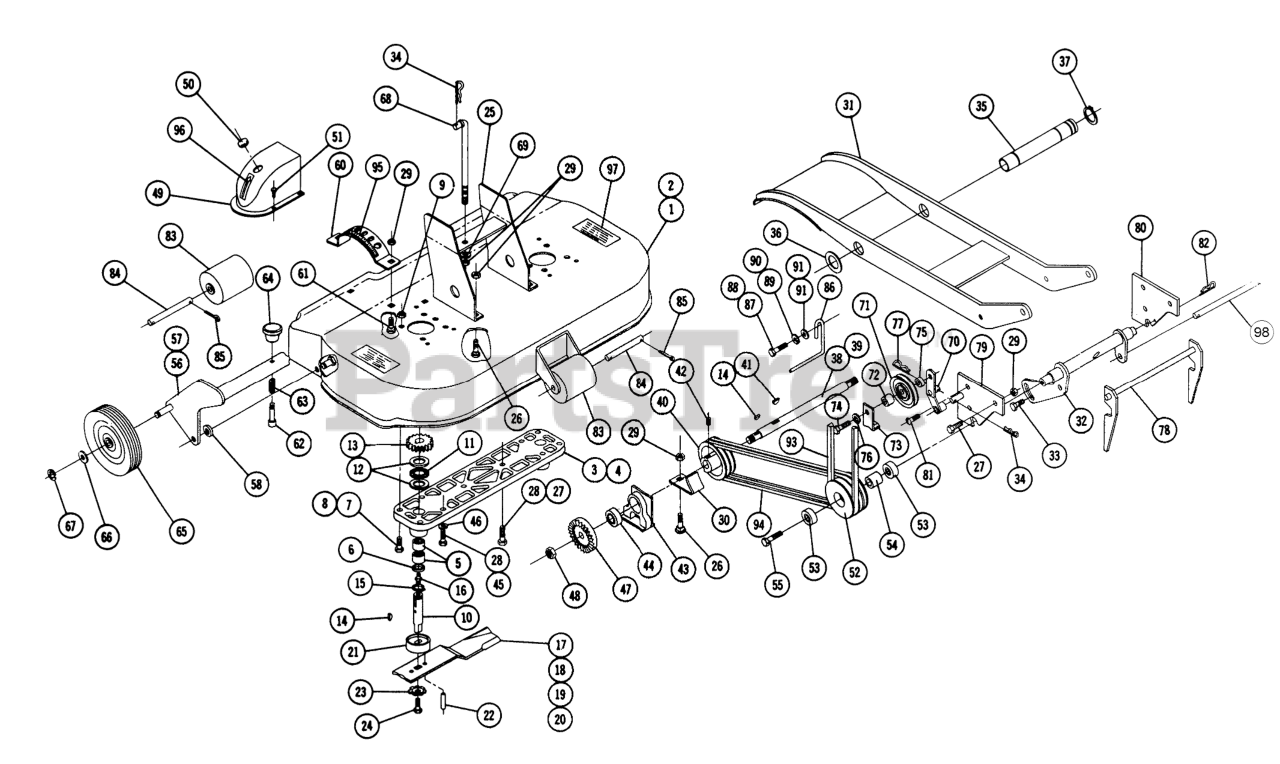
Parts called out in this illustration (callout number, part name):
1	Ass-y. Deck
2	Ass-y Deck
3	Housing
4	Housing
5	NEEDLE BEARING
6	Seal
7	Bolt, 5/16-18 X 7/8
8	Bolt 5/16-18 x 11/4
9	Nut 5/16-18
10	Spindle
11	Bearing Thrust
12	WASHER-THRUST
13	SPUR GEAR
14	WOODRUFF KEY
15	RING-SNAP, EXTERNAL
16	Zerk
17	Blade R.H. 15"
18	Blade L.H. 16"
19	Blade R.H. 18"
20	Blade L.H. 18"
21	SPINDLE CUP
22	SPIROL ROLL PIN
23	WASHER
24	Bolt 3/8-16 x 7/8
25	Ass-y Bracket-Hanger
26	Bolt-3/8-16 x 3/4
27	Bolt 3/8-16 x 1
28	Bolt 3/8-16 x 1
29	3/8-16 E.S.
30	Guard
31	Ass-y-Drag Link
32	ASSY HITCH SHAFT R
33	Bolt Whizlock 3/8-16 x 5/8
34	Hairpin
35	PIVOT TUBE
36	Washer
37	SNAP RING
38	SHAFT CROSS
39	SHAFT
40	PULLEY
41	Key
42	Set Screw
43	BEARING SUPPORT
44	Ball
45	Bolt 3/8-16 x 1
46	Lockwasher
47	Gear
48	Nut 5/18 Elastic Stop
49	COVER GEAR
50	PLUG BUTTON
51	SCREW
52	PULLEY
53	BALL BEARING
54	SPACER-BEARING
55	SPECIAL BOLT
56	Ass-y-Support-Wheel
57	Ass-y Support-Wheel
58	WASHER
59	Bolt-Special
60	QUADRANT R
61	Bolt-3/8-16 x 3/4
62	PLUNGER
63	Spring
64	KNOB
65	WHEEL ASSY
66	SHIM-WASHER
67	E Ring
68	LIFT ROD R
69	Washer
70	Ass-y Idler Arm
71	Pulley
72	SPACER
73	BRACKET GUARD
74	Bolt Hex 3/8-16
75	BUSHING
76	Lockwasher
77	Hairpin
78	Ass-y Latch & Shaft
79	Ass-y Plate Pin R.H.
80	PLATE-MTG BRKT LH R (NS)
81	Bolt 3/8-16 x 1 RD.HD.
82	Hairpin
83	Roller
84	Shaft
85	Cotter Pin
86	RETAINER BELT
87	Bolt Round Head 5/16-24 x 3/4
88	Bolt 3/8-16 x 3/4
89	Lockwasher
90	Lockwasher
91	Washer
92	Washer
93	V Belt-28"
94	V-BELTS - MATCHED PR
95	Decal-Height Control
96	Decal
97	Decal
98	Pin-Hitch
